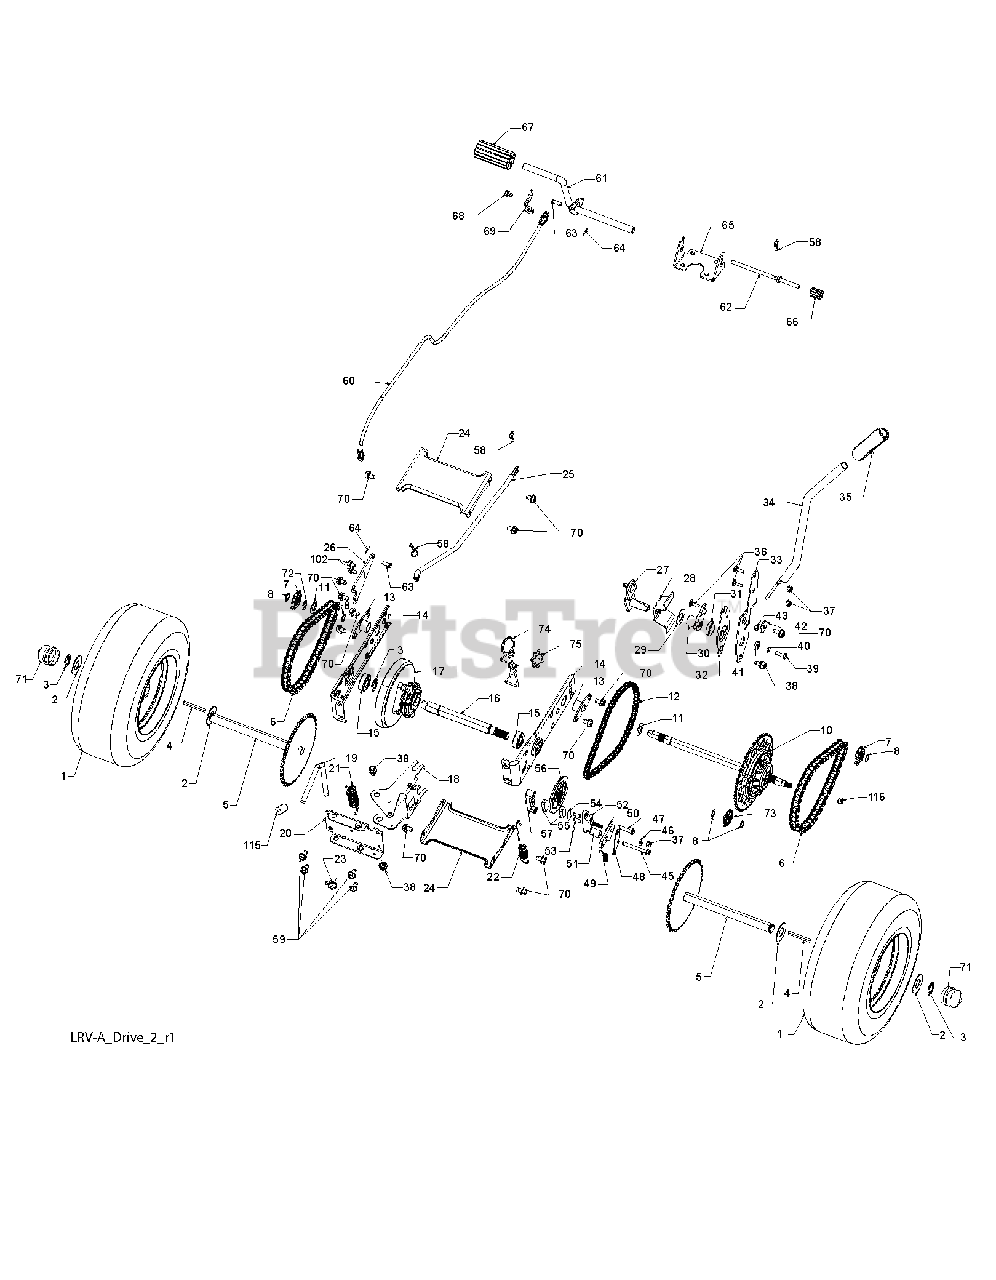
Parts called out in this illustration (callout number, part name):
1	WHEEL.ASM.REAR.LRV.13"MS613
3	E-RING LT
4	SQUARE KEY
5	WELDMENT.AXLE.DRIVEN
6	CHAIN.DRIVE
7	SPROCKET.9.TOOTH.SPLINED
8	SNAP RING
10	DIFFERENTIAL ASM LRV
11	THRUST WASHER
12	CHAIN, PRIMARY DRIVE
13	BUSHING.FLANGE.5/8
14	BRACKET.CARRIER
15	BEARING.BALL
16	SHAFT.INPUT.LRV
17	SUBASM.WHEEL.FRICTION
18	ARM, SHIFT
19	ROD.BYPASS.LRV
20	BRACE CARRIER REAR
21	SPRING, CARRIER
22	SPRING, BRAKE
23	SPRING, BYPASS
24	BRACE CARRIER BOX
26	ARM. CLUTCH.LRV
27	WELDMENT SHIFT LEVER
28	RP SUPPORT, SHIFT LEVER
29	WASHER NYLON
30	HUB.SHIFT
31	SPACER.NYLON.
32	MNTG BRKT. SHIFT ARM
33	BRACKET, SHIFTER FLEX
34	TUBE SHIFT ARM
35	GRIP.LEVER.5625.ID
37	LOCKNUT.NYLOC.1/4-20
38	BOLT.SHOULDER.5/16-18X
40	LOCKWASHER
41	WASHER LT
42	WASHER.SRRTD.5/16
43	NUT.CROWNLOCK.1/4
45	SCREW.HXWH.THDRL.1/4-20X2.25
46	WASHER
47	SCREW.HXWH.THDRL.1/4-20X1-1/4
48	PLATE.ANTI-ROTATION.BRAKE
49	SPRING, BRAKE RETURN
50	ARM.BRAKE
51	SPACER.RETURN.BRAKE.LRV
52	CALIPER.BRAKE.ASM
53	PIN.DOWEL
54	PLATE, BRAKE PAD
55	PUCK BRAKE
56	ROTOR.BRAKE
57	CAP, BRAKE CALIPER
59	SCREW LT
60	RP CABLE.BRAKE.
61	SHAFT.ASM.PEDAL.LRV
62	ROD.BRAKE.PARK.LRV
63	PIN.CLEVIS
64	COTTER PIN
65	BRACKET.SUPPORT.BRAKE.LRV
66	COVER.PEDAL.BRAKE.PARKING.LRV
67	COVER.PEDAL.BRAKE.LRV
68	SCREW.1/4-20X3/8
69	BRAKE.MOUNT.CABLE.LRV
70	SCREW
71	CAP.HUB.AXLE.LRVA/B
72	RETAINING RING LT
73	SPROCKET.11 TOOTH.SPLINED
74	TENSION.LRV.CHAIN
75	SPROCKET.IDLER.7TOOTH.LRV
115	CAP.PLUNGER.BLACK
116	NUT LOCK FLG 3/8-16 UNC
